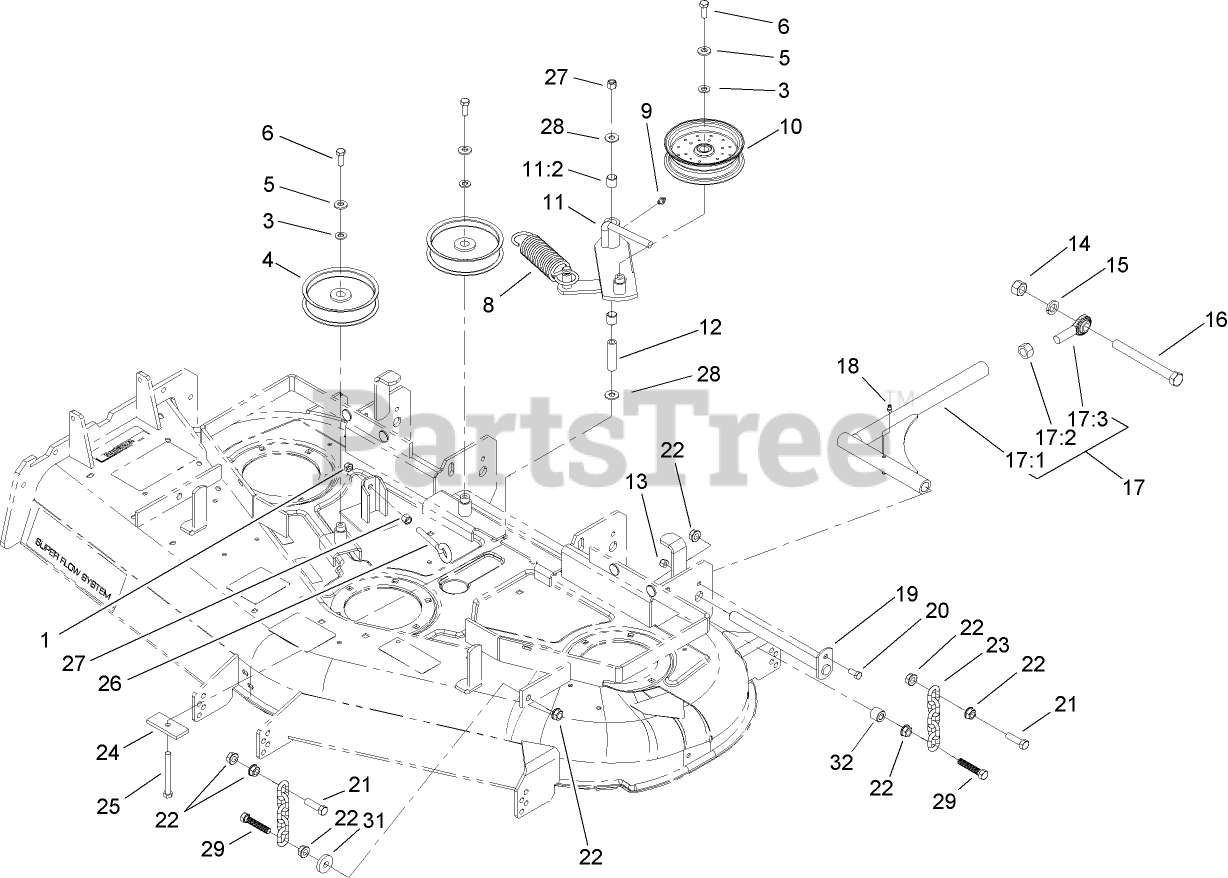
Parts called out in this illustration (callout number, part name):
1	NUT-HEX
3	WASHER-FLAT
4	PULLEY-IDLER
5	WASHER-BELLEVILLE
6	SCREW-HH
8	Spring-Extension
9	FITTING-GREASE, 90 DEG
10	PULLEY-IDLER
11	IDLER ARM ASM
11:2	SLEEVE-BEARING
12	BUSHING-PIVOT, IDLER
13	NUT-LOCK, NI
14	NUT-HEX
15	WASHER-LOCK
17	STRUT ASM
17:1	STRUT
17:2	NUT-HEX
17:3	BALLJOINT-SPHERICAL
18	FITTING-GREASE
19	PIN-STRUT
20	SCREW-HH
21	SCREW-HH
22	NUT-HF
23	CHAIN-LIFT, DECK
24	PLATE-RETAINER, BOLT
25	SCREW-HH
26	BOLT-EYE
27	NUT-LOCK, NI
28	WASHER-HARDENED
29	SCREW HH
31	WASHER
32	SPACER-BEDBAR
